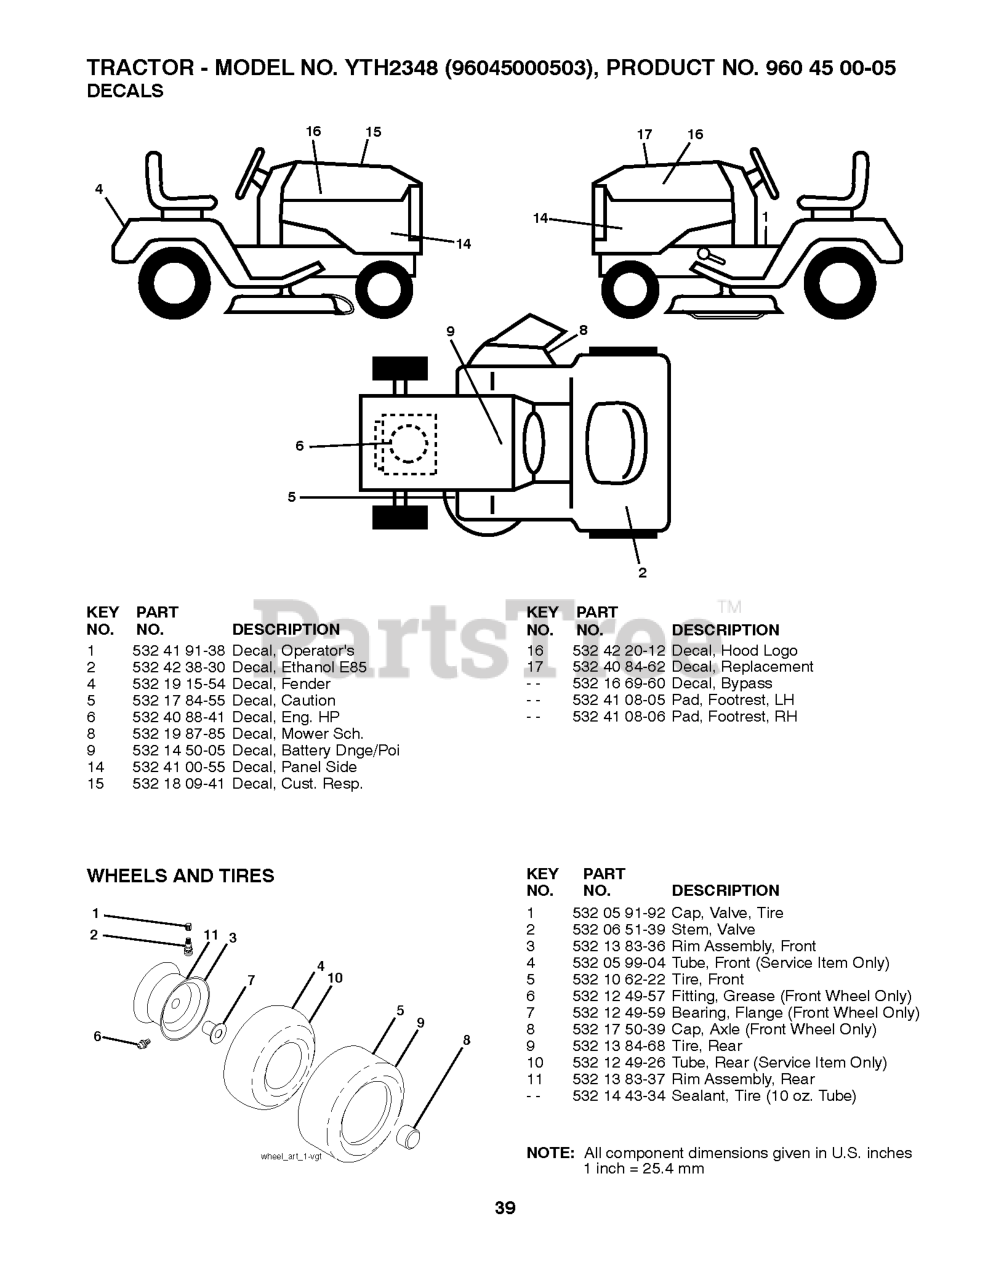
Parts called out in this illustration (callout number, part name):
2	VALVE STEM LT
3	RIM ASM 6" FRONT SILVER
4	TUBE.5.3/4.5/6
5	TIRE HEAVY DUTY
6	FITTING LT
7	BEARING T
8	CAP, AXLE BLK
9	TIRE.20X8-8.TURF.SAVER
10	TUBE
11	RIM ASM 8" REAR SILVER
